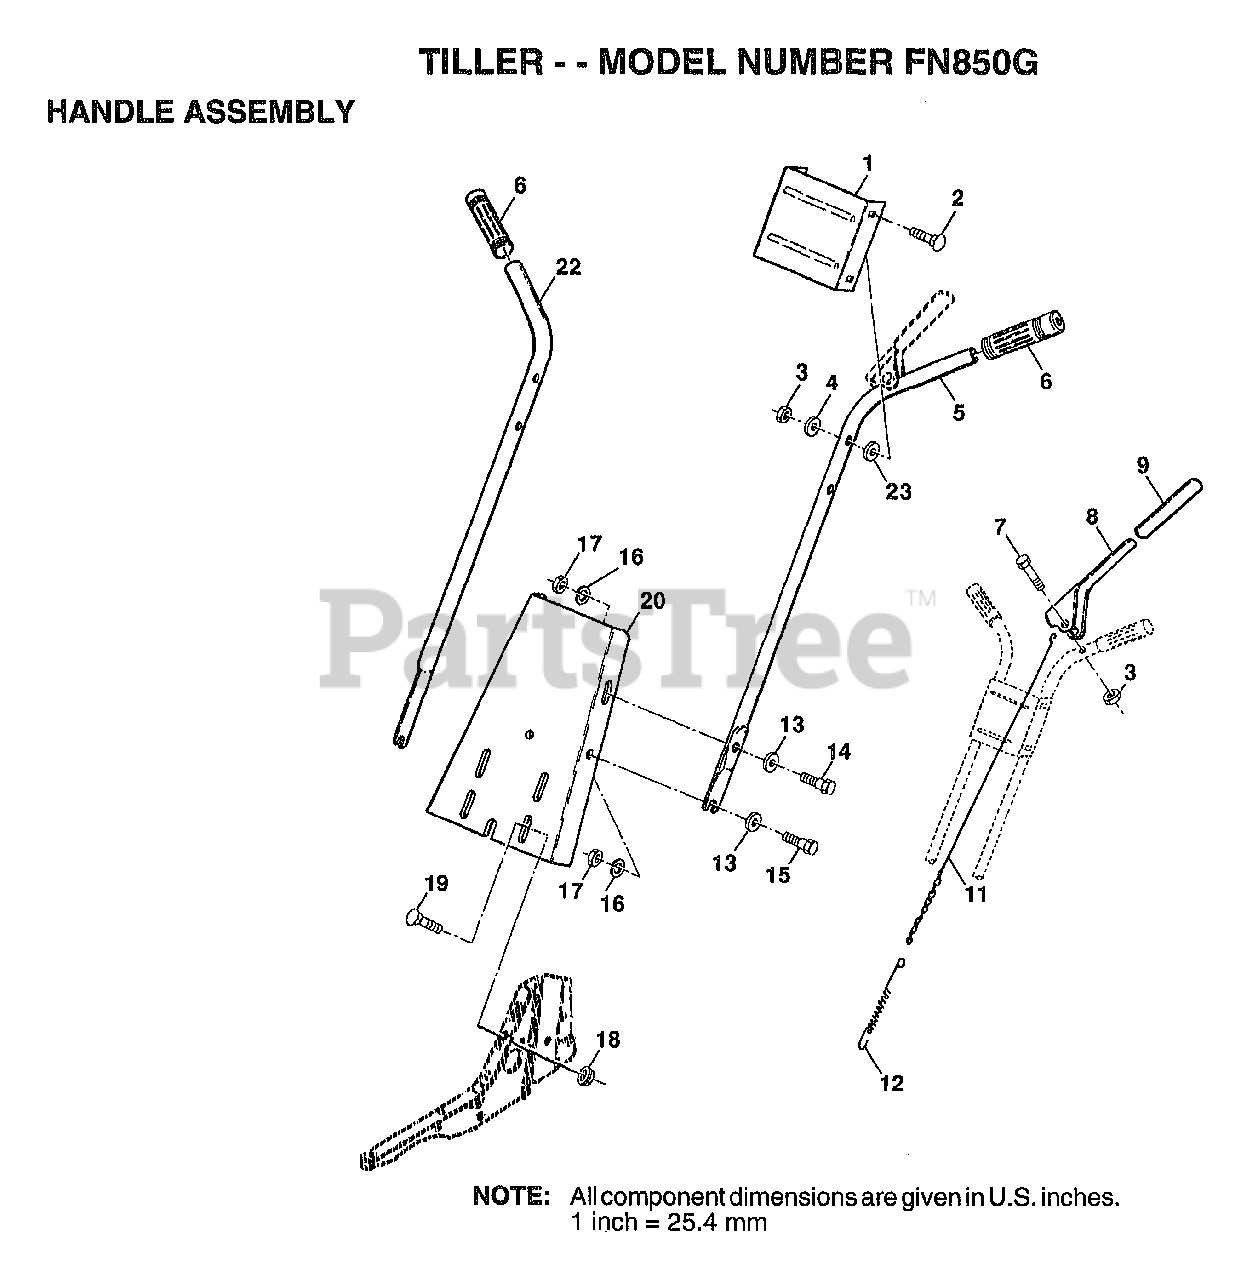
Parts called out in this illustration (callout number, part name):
1	HANDLE BRKT
2	BOLT
4	WASHER
5	HANDLE LH
7	BOLT.HEX.5/16-1.5
9	GRIP T
12	SPRING EXT TI
13	WASHER
15	BOLT
16	LOCKWASHER
17	NUT.HEX.5/16-18
18	NUT
19	BOLT
20	PANEL. HANDLE
22	HANDLE RH
23	WASHER
